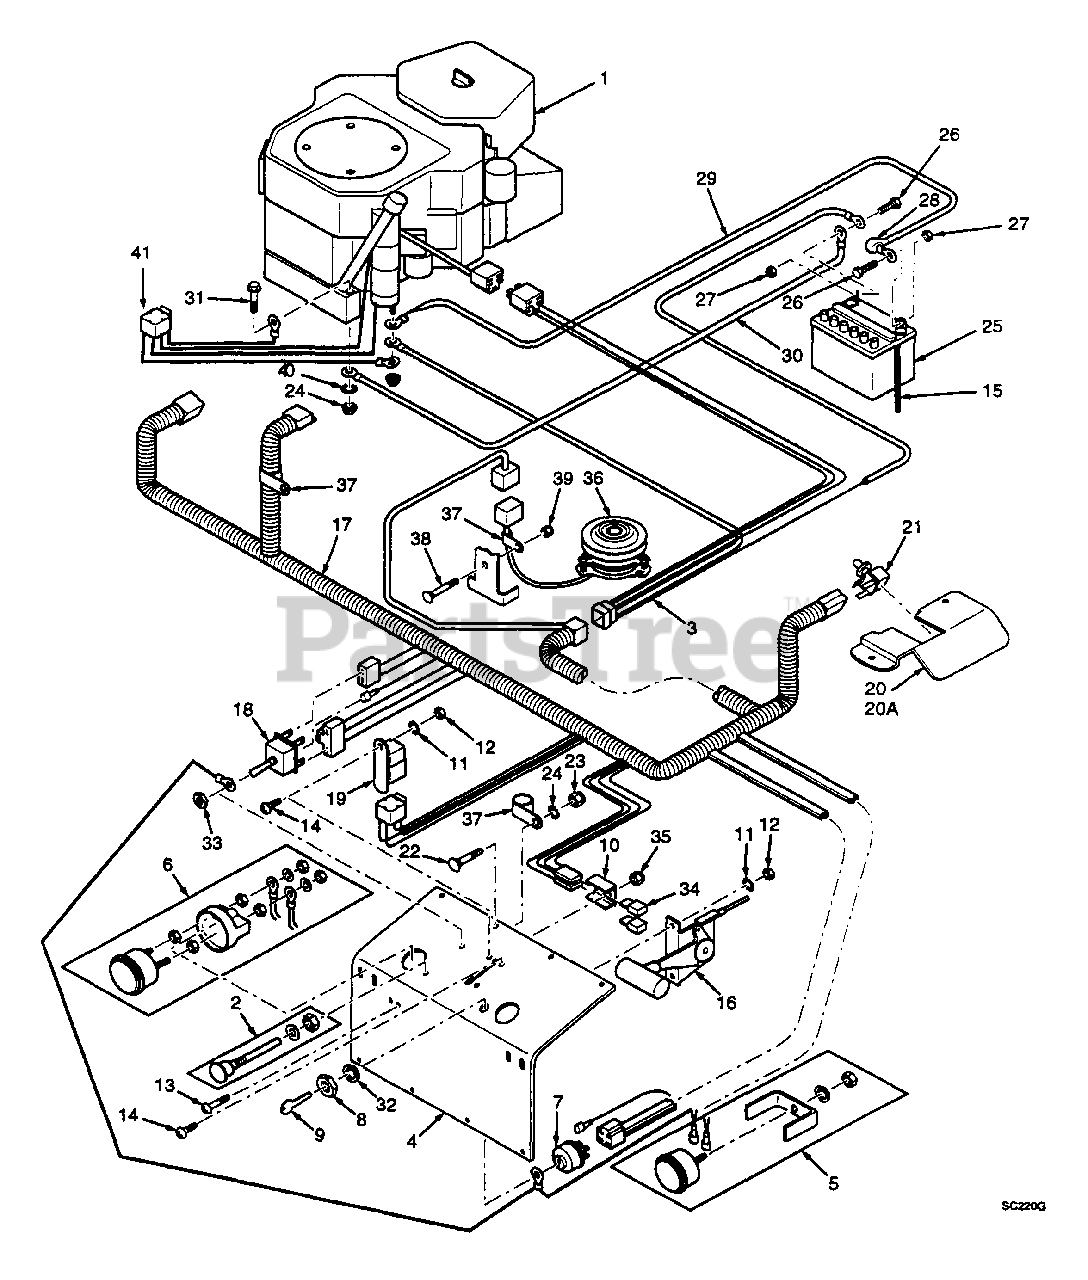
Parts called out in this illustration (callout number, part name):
1	Engine 18 hp Kohler CV
2	Choke Control
3	Adapter
4	Kick Plate
5	Hour Meter
6	Ammeter
7	Key Switch
8	Nut, Hex 5/8-32
9	Key & Ring Assembly
10	Bracket, Fuse Holder
11	Lockwasher, #10 External Tooth
12	Nut, Hex #10-32
13	Screw, Phillips Washer Head #10-32 x 1-1/2"
14	Screw, Phillips Washer Head #10-32 x 1/2"
15	Overflow Tube
16	Throttle Control
17	Wire Harness
18	Switch, Mower Engagement Electric Clutch
19	Relay
20	Neutral Lock Bracket, RH
20A	Neutral Lock Bracket, LH
21	Switch Neutral Lock
22	Bolt, Carriage 5/16-18 x .75"
23	Nut, Elastic Stop 5/16-18
24	Nut, Serrated Flange Hex 5/16-18
25	Battery
26	Bolt, Hex Head 1/4-20 x 1/2"
27	Nut, Hex 1/4-20
28	Rubber Boot
29	Battery Cable, 25" Red
30	Battery Cable, 27" Black
31	Bolt, Serrated Range Hex Head 5/16-18 x 1.50"
32	Lockwasher. 5/8" Internal
33	Nut, Hex 1/2-27
34	Fuse, Blade Type 20 amp
35	Nut, Elastic Stop #10-32
36	Electric Clutch
38	Bolt, Carriage 5/16-18 x 3/4"
39	Nut, Elastic Stop 5/16-18
40	Lockwasher, 5/16" Internal Tooth
41	Wire Harness W/Relay
